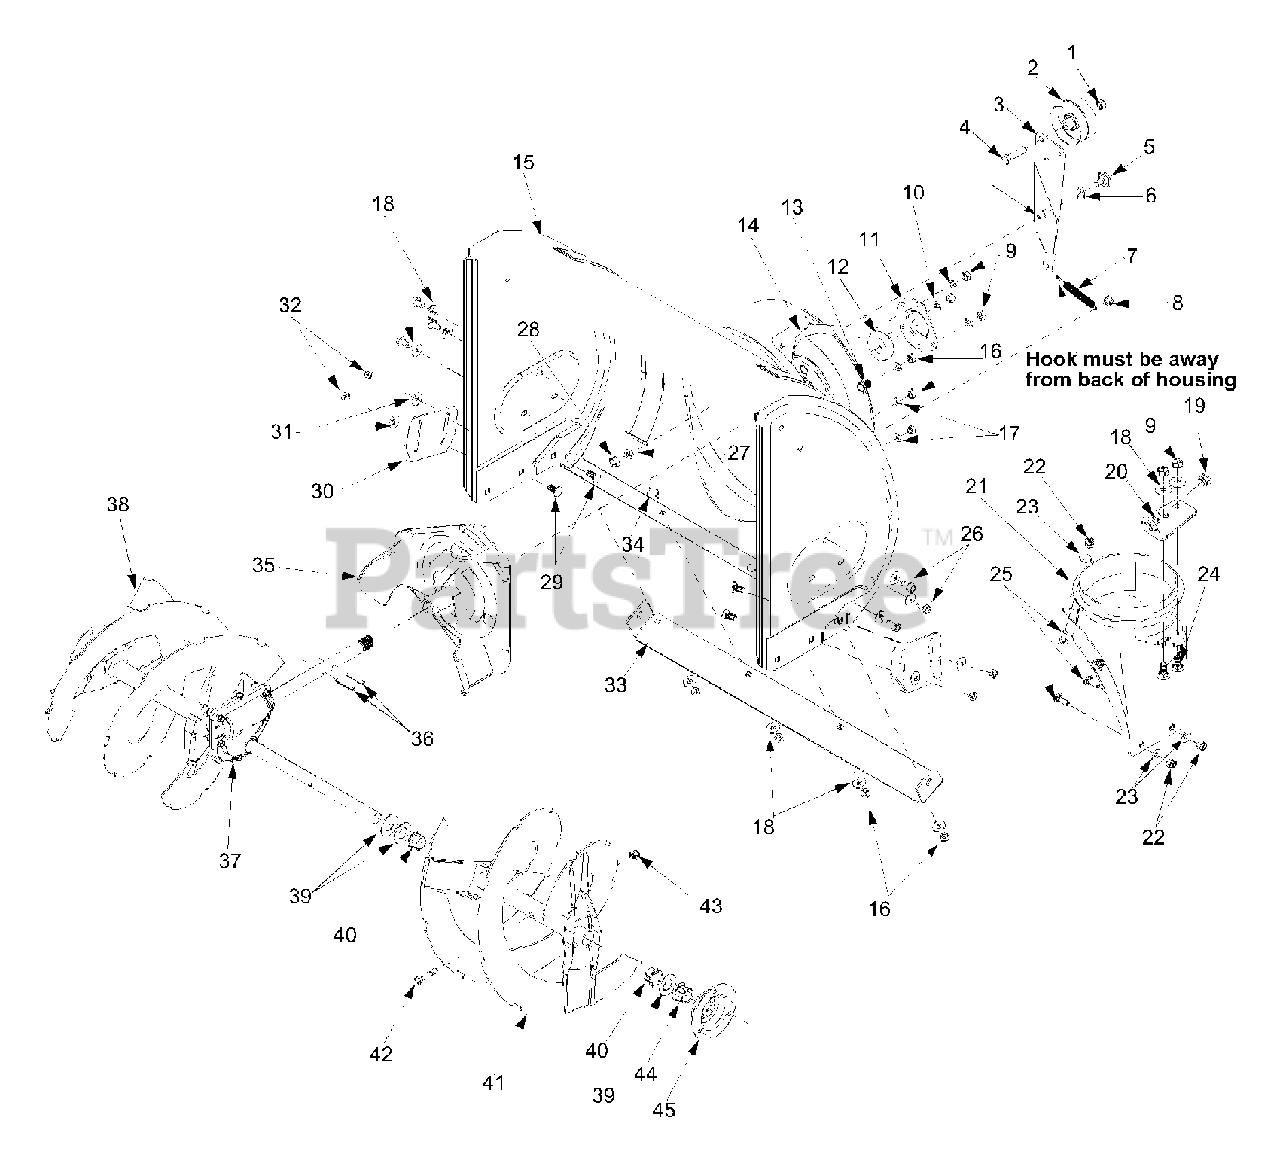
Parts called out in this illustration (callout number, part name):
1	Lock Jam Nut 3/8-24
2	Flat Idler
4	Hex Cap Screw 3/8-24 x 1.50
5	Shoulder Screw
6	Wave Washer
7	Extension Spring
8	Hex Nut 5/16-18
9	Hex Nut 5/16-18
10	Lock Washer 5/16
11	Housing
12	Ball Bearing
13	Carriage Bolt 5/16-18
17	Lock Washer 5/16
18	Bell Washer
19	Bushing
21	Chute Adapter
22	Hex Lock Nut 1/4-20
23	Flat Washer
24	Carriage Bolt
25	Carriage Screw 1/4-20 x .75
26	Hex Washer Screw 5/16-18
27	Lock Washer 3/8
28	Hex Nut 3/8-16
29	Carriage Bolt 5/16-18 x .75
31	Bell Washer
32	Hex Nut 5/16-18
34	Carriage Bolt 5/16-18 x .62
37	22" Gear Assembly
40	Flange Bushing
42	Shear Bolt 5/16-18 x 1.5
43	Lock Nut 5/16-18
44	Hex Flange Bearing
